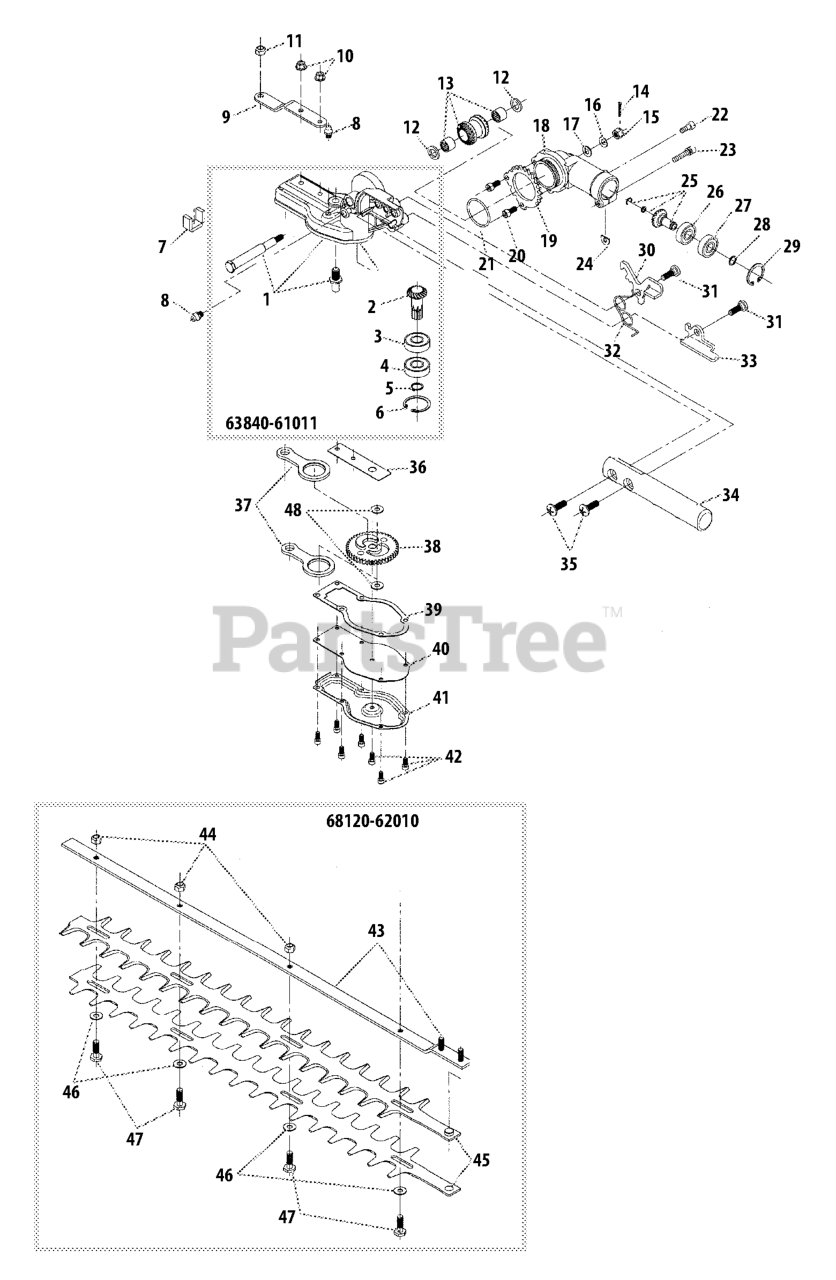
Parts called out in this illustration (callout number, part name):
1	CASE, GEAR - LOWER
2	GEAR - SHAFT
3	BEARING, BALL - 6001
4	BEARING, BALL - 6001ZZ
5	RING, RETAINING - 12
6	RING, RETAINING - 28
7	SEAL, FELT
8	FITTING, GREASE
9	BRACKET, CUTTER
10	NUT - 5 -- FLANGE
11	LOCKNUT
12	COLLAR
13	GEAR SET - BEVEL
14	PIN, SPLIT
15	NUT - CASTLE
16	WASHER - CONICAL
17	WASHER - 6
18	CASE, GEAR - UPPER
19	PLATE, ADJUST
20	SCREW - 5X12
21	O-RING
22	SCREW - 5X12
23	SCREW - 5X25
24	SHIM
25	GEAR - BEVEL
26	BEARING, BALL - 609
27	BEARING, BALL - 609ZZ
28	RING, RETAINING
29	RING, RETAINING - 24
30	LEVER, LOCK
31	SCREW
32	SPRING
33	LEVER, LOCK
34	HANDLE
35	SCREW - 6X20
36	PLATE
37	ROD, CONNECTING
38	CAM GEAR
39	GASKET
40	PLATE, GEAR CASE
41	CASE, GEAR - LOWER
42	SCREW - 4X10
43	GUIDE BAR - 22" (55cm)
44	LOCKNUT
45	BLADE - 22" (55cm)
46	WASHER - 6
47	BOLT - 6X20
48	SPACER
63840-61011	GEAR CASE ASSY
68120-62010	BLADE KIT - 22" (55cm)
